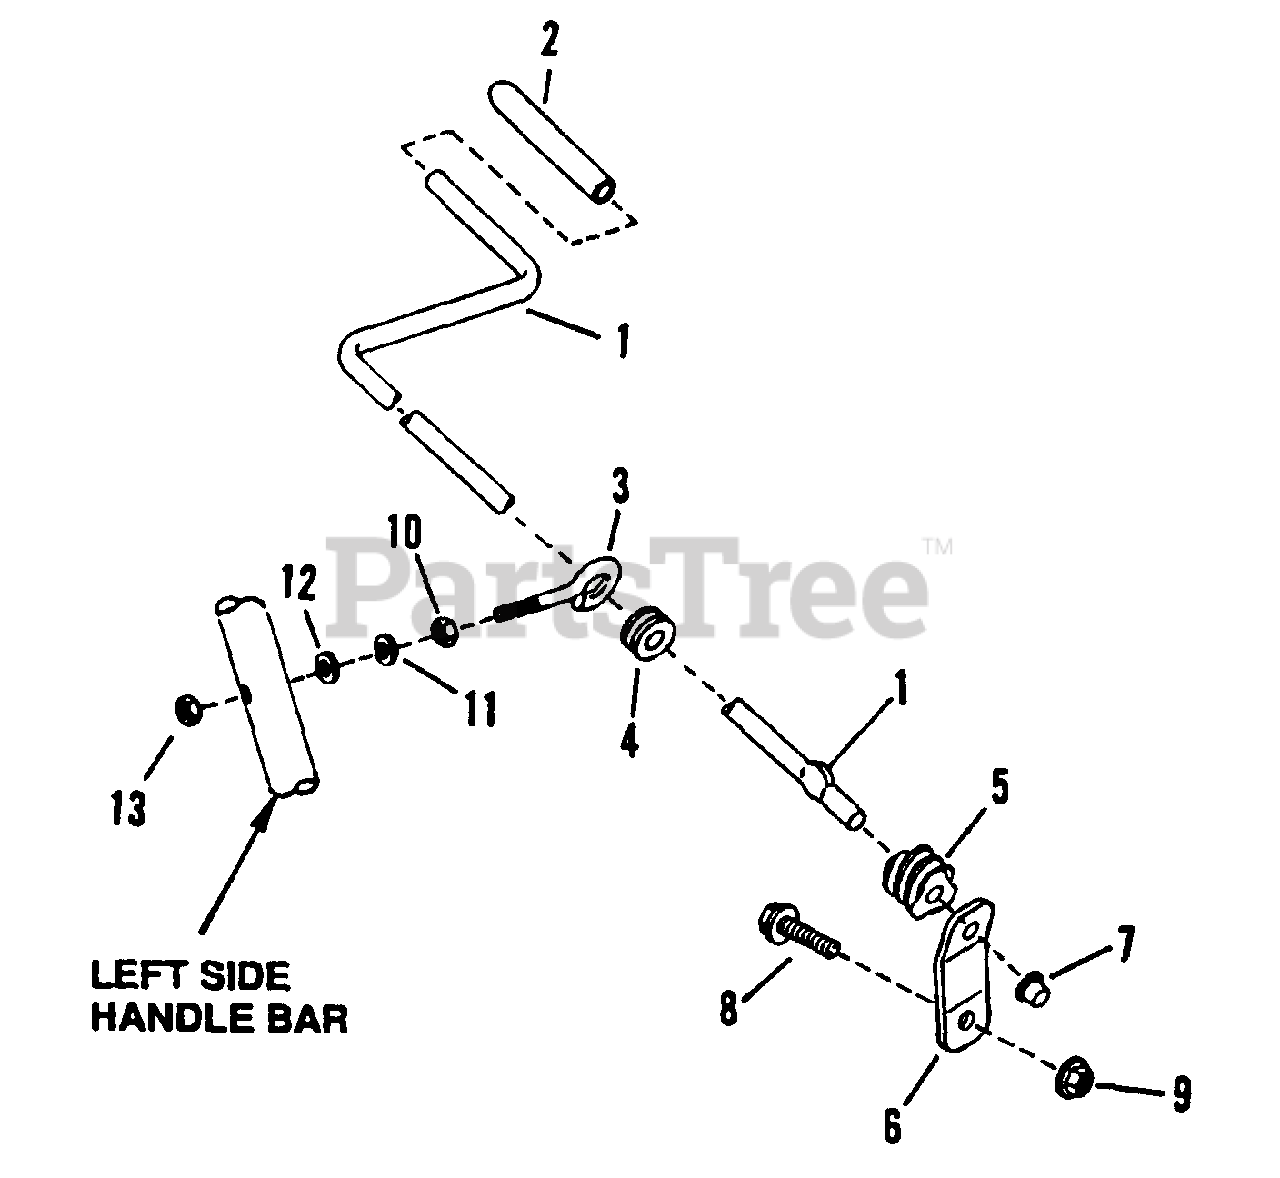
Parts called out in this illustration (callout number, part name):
1	CRANK, Chute
2	GRIP, Vinyl
3	EYE-BOLT, 5/16-18"
4	GROMMET
5	WORM (Plastic)
6	BRACKET, Worm Mounting
7	PUSH-NUT, 3/8"
8	SCREW, 5/16-18 x 5/8" Hex Head Cap, Grade 5
9	NUT, 5/16-18 H. Fl. Lock, Gr. 5
10	NUT, 5/18-18 Hex
11	WASHER, 5/16 Int. Tooth Lock
12	WASHER, 5/16 Flat
13	NUT, 5/16-18 Hex Center Lock
